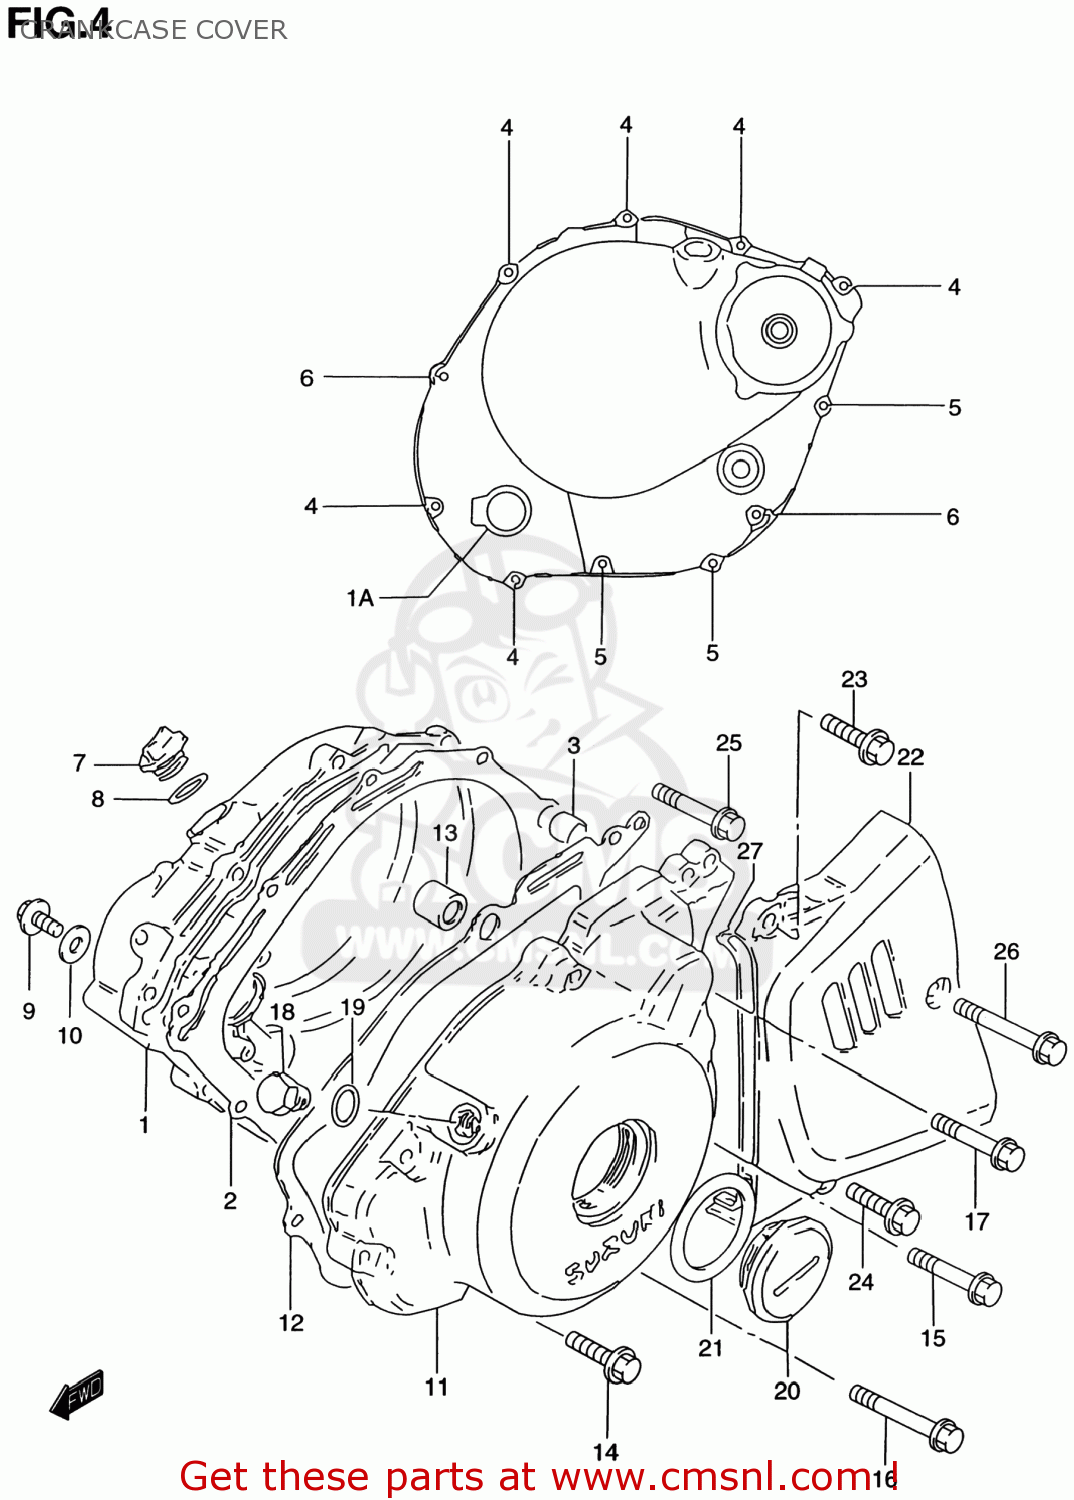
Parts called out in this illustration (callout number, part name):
1	COVER,CLUTCH
1A	LENS,OIL LEVEL CHECK
2	GASKET,CLUTCH COVER (NAS)
3	PIN
4	BOLT
5	BOLT
6	BOLT
7	PLUG(20X10)
8	O RING(D:3.1,ID:16.8)
9	PLUG (14X12)
10	GASKET(13.8X18.8X4.8) (NAS)
11	COVER,MAGNETO
12	GASKET,MAGNETO COVER (NAS)
13	PIN
14	BOLT
15	BOLT
16	BOLT
17	BOLT
18	PLUG,12X9
19	GASKET(12.1X16.2X3.7) (NAS)
20	PLUG,36X10
21	O RING(D:3.1,ID:32.7)
22	COVER,ENGINE SPROCKET
23	BOLT
24	BOLT
25	BOLT
26	BOLT
27	DAMPER,ENGINE SPROCKET COVER
